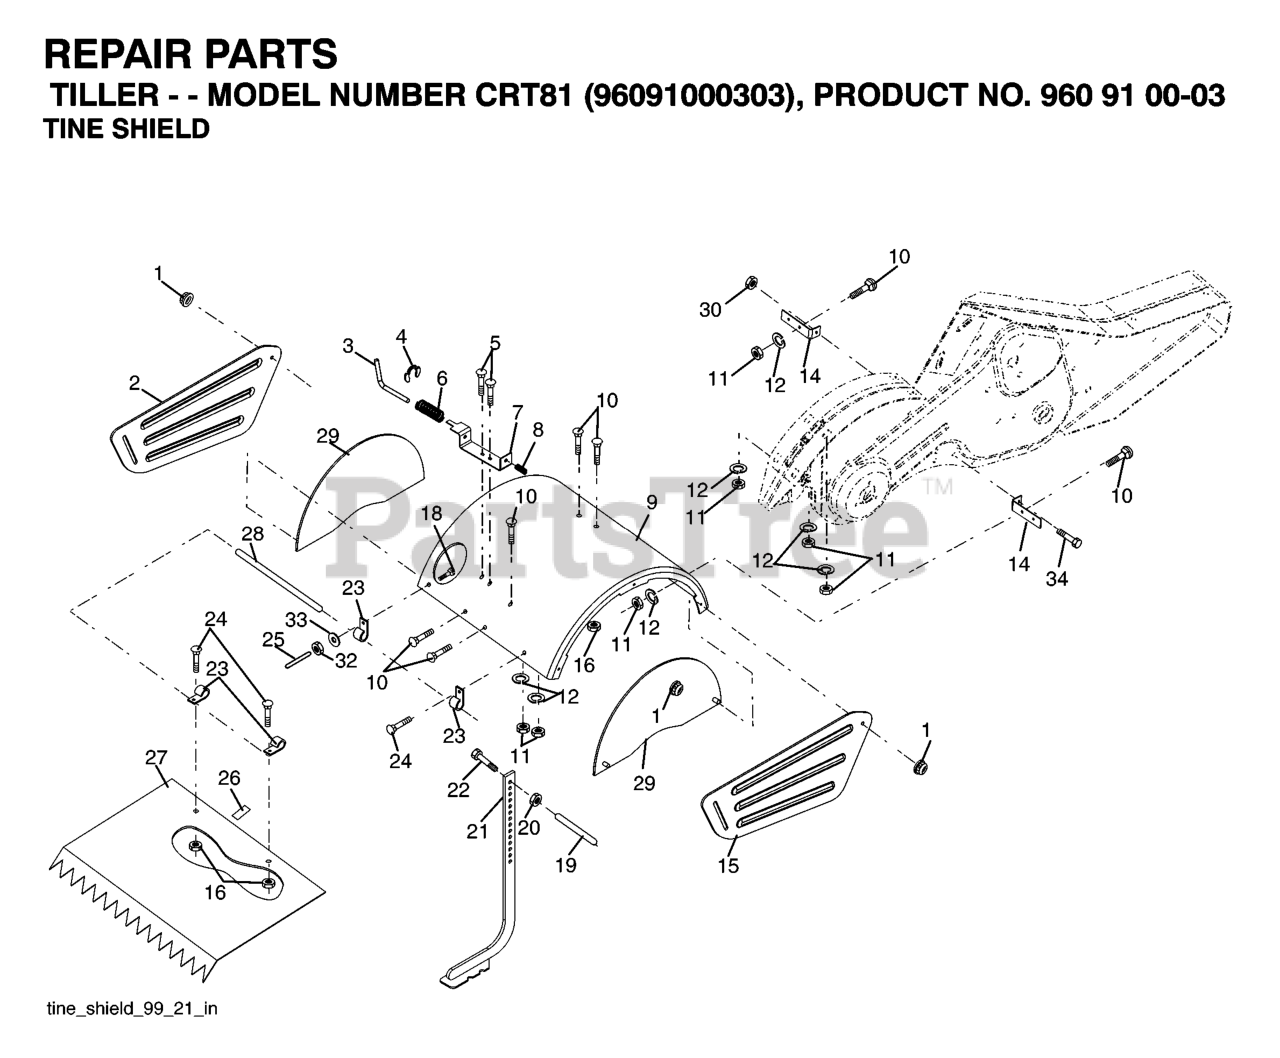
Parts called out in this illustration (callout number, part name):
1	NUT LOCK HEX FLANGE 5/16-18
2	TINE SHIELD
3	STAKE PIN TI
4	RING, KLIP
7	BRACKET.LATCH.STAKE.3.20.BLACK
8	SPRING CRT
9	SHIELD TINE
10	BOLT, RDHD SQNK 5/16-18 X 3/4
12	WASHER.LOCK.HVY.HLCL.SPR.5/16
14	BRACKET.TINE.SHIELD.TILLER
15	SHIELD
16	NUT T
20	NUT.HEX.3/8-16UNC
21	STAKE.ASM.DEPTH
22	BOLT.375-16
25	VINYL CAP TI
26	PAD IDLER TI
27	SHIELD.LEVELING.21".ORANGE
28	PIN, HINGE
29	SHIELD, SIDE
30	LOCKNUT-FLANGE 5/16-18
32	NUT
33	LOCKWASHER
34	Bolt Hex Flanged 5/16-18 Unc x 2
